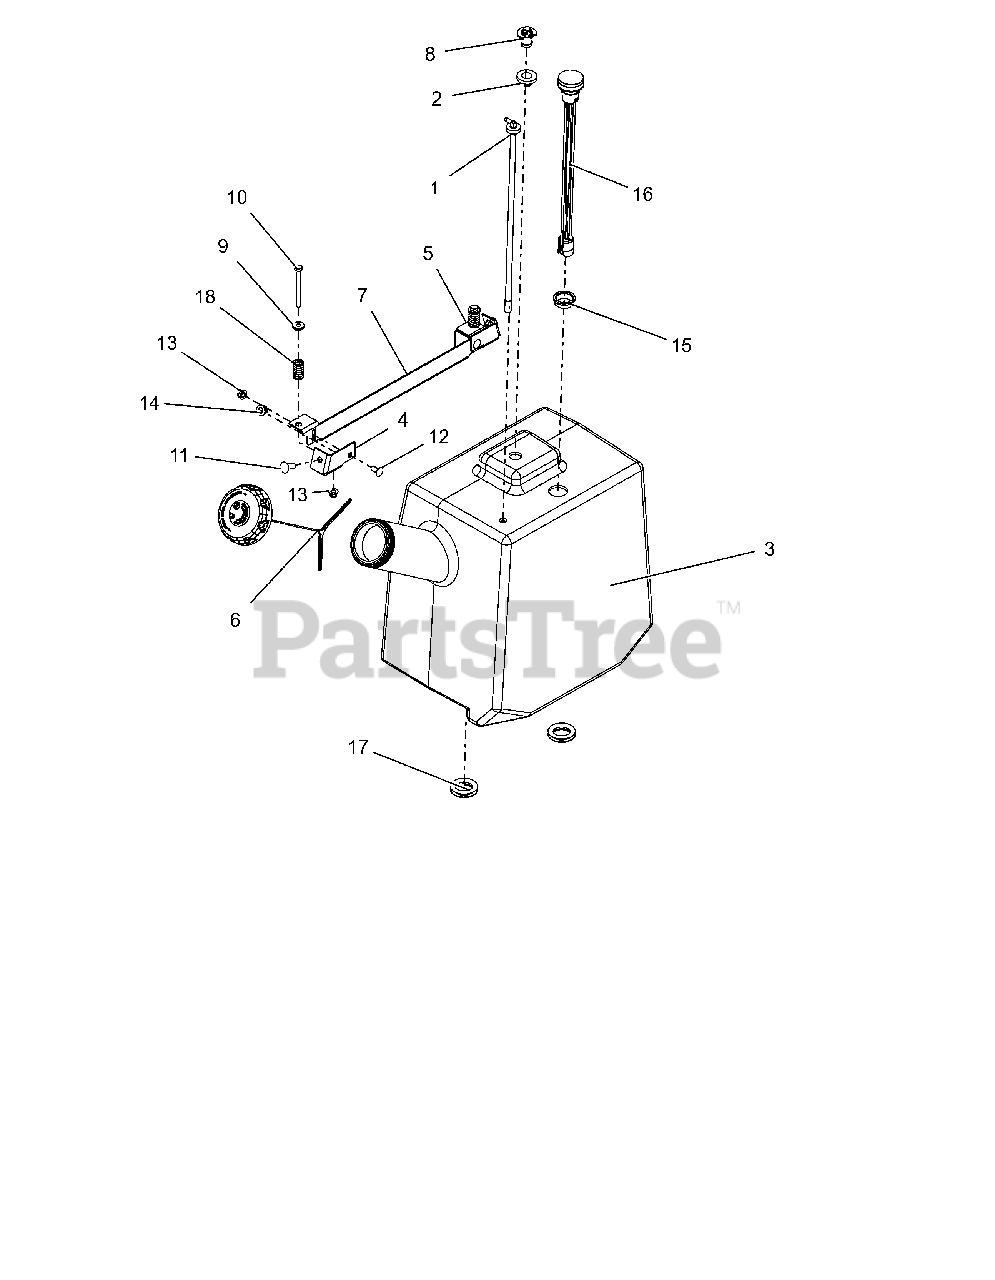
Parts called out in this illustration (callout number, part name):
1	ASS'Y, PROSTANCE FUEL PICK-UP
2	GROMMET, REMOTE VENT NITRILE
3	TANK, PROSTANCE FUEL
4	MOUNT, FUEL TANK HOLD DOWN-RH
5	MOUNT, FUEL TANK HOLD DOWN-LH
6	CAP, FUEL VENTIN AUTOLOCK
7	HOLDDOWN, FUEL TANK
8	VALVE, 2-WAY
9	BSHG-FLG .32X.500X.344X.880
10	@BLT-HEX .31-18X3.25 GR5 YWZC
11	@BLT-RDHDSHSQNK.38-16X1.0 G5YZ
12	@BLT-RDHDSQNK .31-18X.75 G5YZ
13	@NUT-LK-NYL-FLG .31-18 YWZC
14	@NUT-LK-NYL-FLG .38-16 YWZC
15	GROMMET, FUEL GAUGE
16	GAUGE, REMOTE FUEL SEALED 15"
17	GROMMET 1.25ID X 1.5OD
18	SG-COMP .125X.781X1.250
